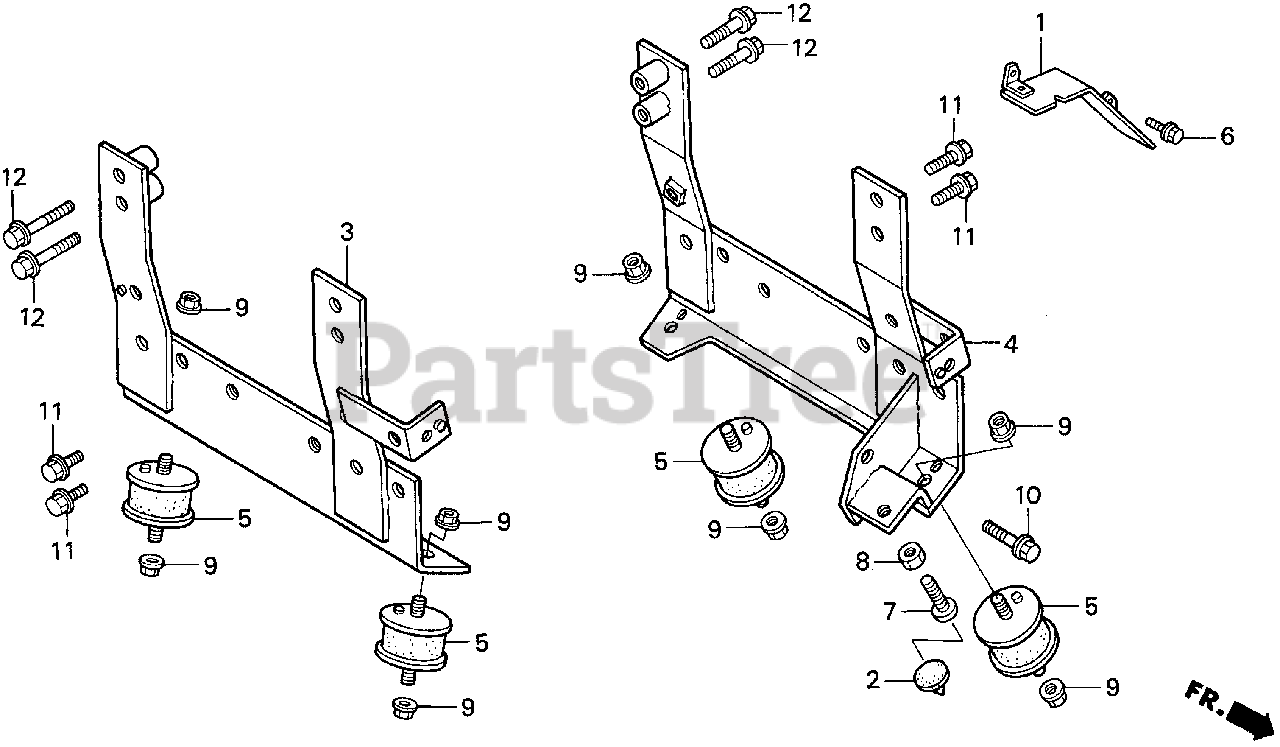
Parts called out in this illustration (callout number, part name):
1	COVER, FLYWHEEL
2	PAD, PEDAL STOPPER
3	BRACKET, R. ENGINE MOUNT
4	BRACKET, L. ENGINE MOUNT
5	RUBBER, ENGINE MOUNTING
6	BOLT, FLANGE (6X14)
7	BOLT, STOPPER (12X26)
8	NUT, HEX. (12MM)
9	NUT, FLANGE (10MM)
10	BOLT, FLANGE (8X22)
11	BOLT, FLANGE (10X25)
12	BOLT, FLANGE (10X45)
